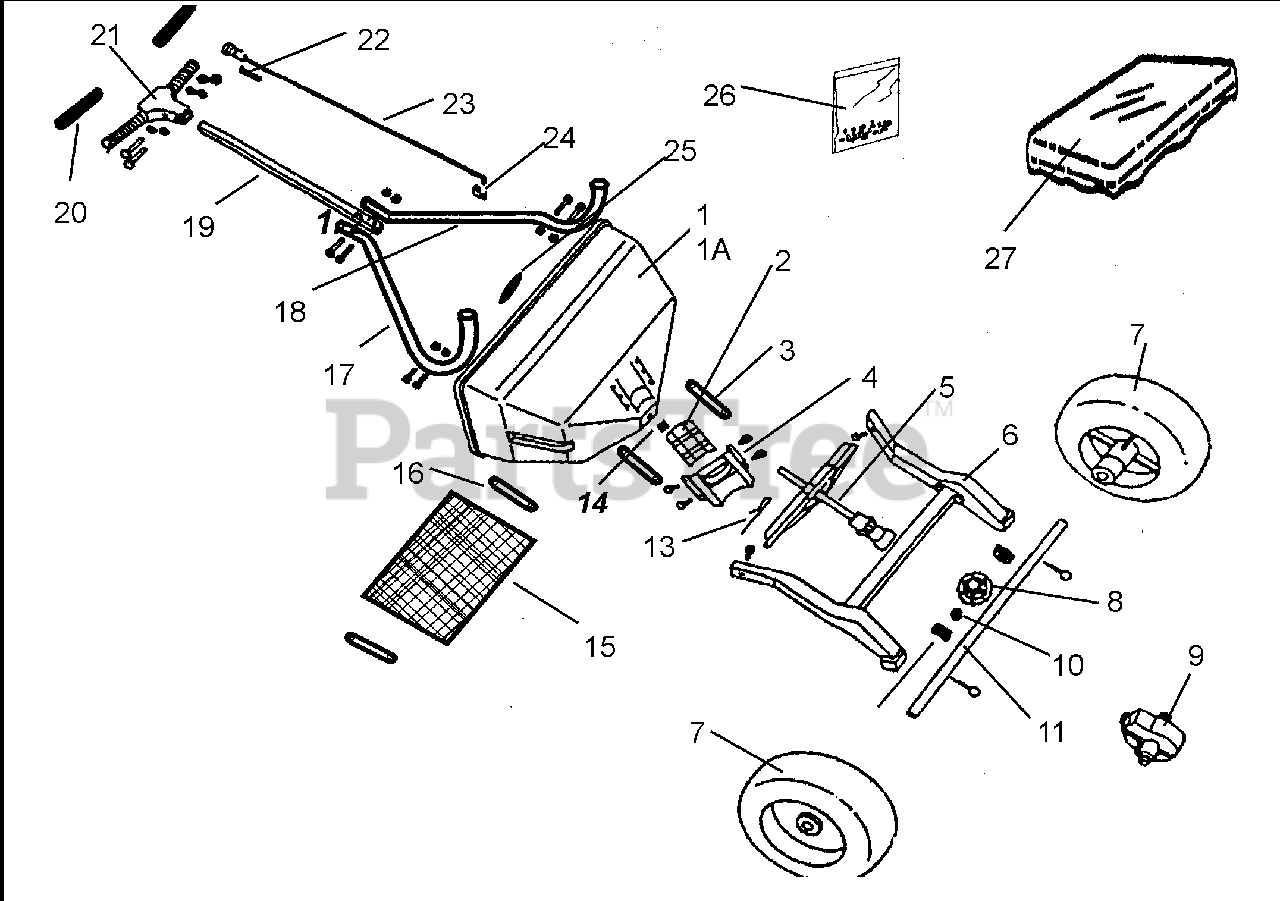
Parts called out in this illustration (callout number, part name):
1A	HOPPER ASSY
2	SHUTOFF PLATE
4	RATE CAM & CHUTE ASSY
5	IMPELLER ASSY
6	FRAME ASSY
7	WHEEL KIT
8	GEAR, AXLE
9	COVER, GEAR
10	AXLE COLLAR W/ SET SCREW
11	AXLE
12	BUSHING
13	AGITATOR
14	BEARING
15	SCREEN, HOPPER
16	CLIP
17	Handle Brace W/ Plug- LH.
18	Handle Brace W/ Plug- RH.
19	TUBE, HANDLE
20	GRIP, HANDLE
20	T-HANDLE ASSY
22	CONTROL KNOB SPRING
23	Control Knob & Wire Ass’y.
24	CLIP
25	PLUG
26	FASTENER KIT
27	COVER, HOPPER
